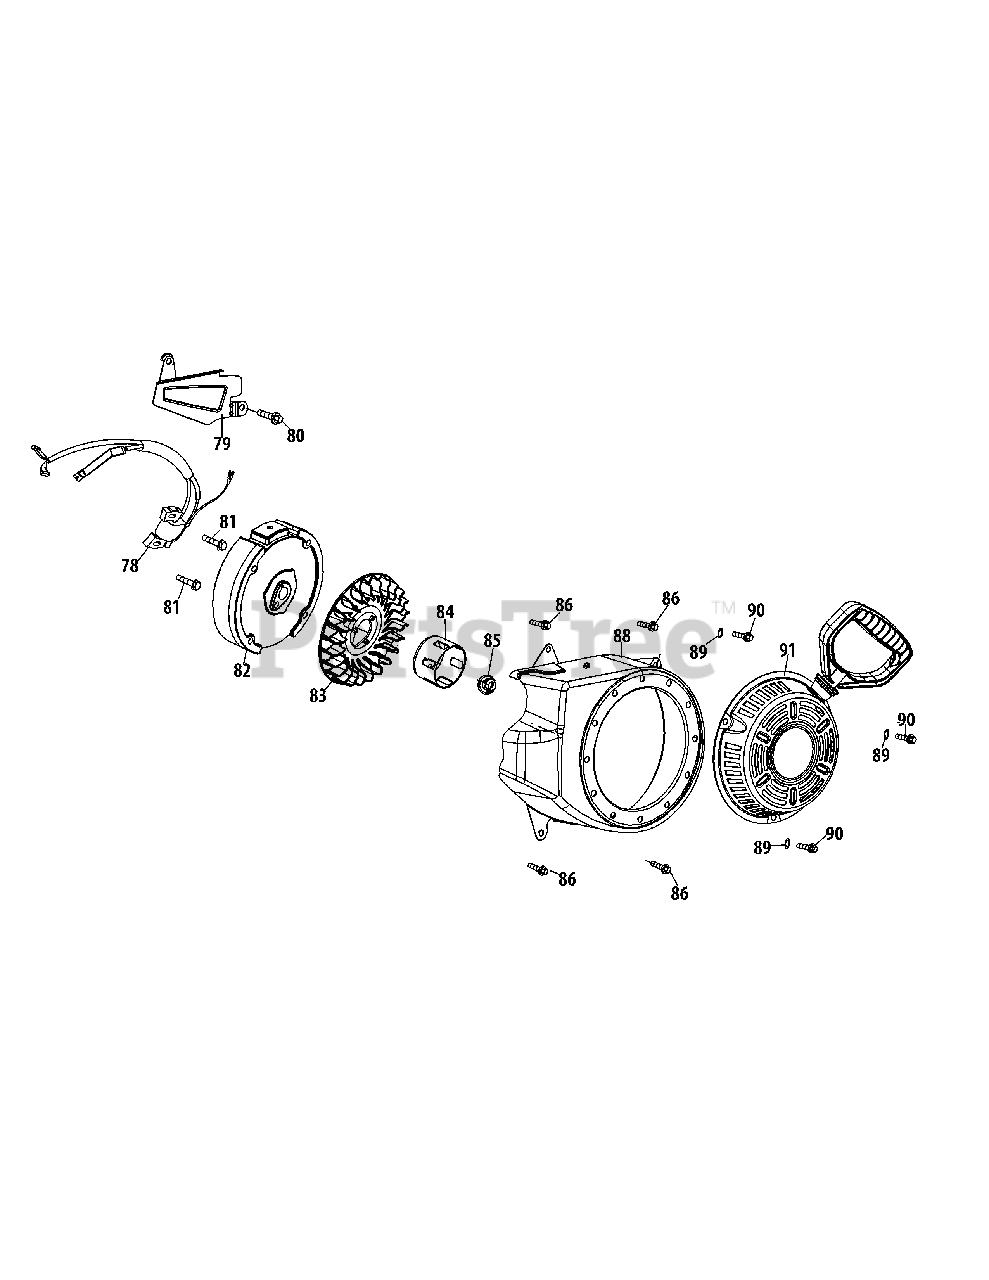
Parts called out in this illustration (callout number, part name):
78	Ignition Coil Assembly
79	Air Flow Shield
80	Bolt M6×10
81	Bolt M6×25
83	Cooling Fan
84	Starter Cup
85	Nut, Special, M14×1.5
86	Bolt M6×12
88	Blower Housing
89	Flat Washer
90	Bolt M6×10
91	Recoil Starter
